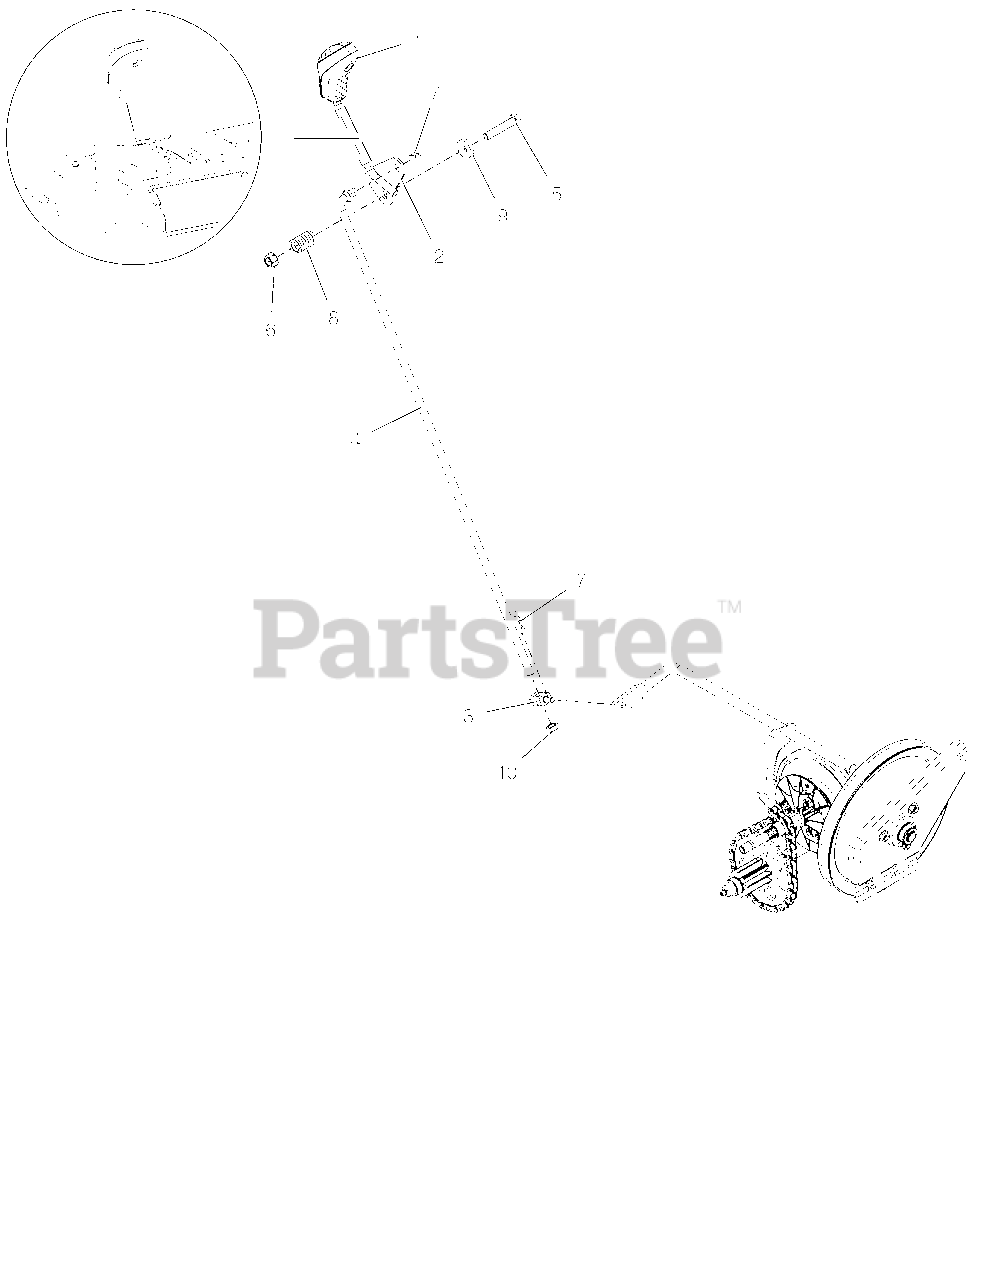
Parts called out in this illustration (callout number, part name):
1	KNOB, CONTROL, DASH
2	WELDMENT,LG DASH SPEED CONTROL
3	PIVOT,SHIFT ROD .375-16(TRUNN)
4	ROD, SHIFT-PRO
5	@BLT-HEX .38-16X2.00 GR5 YWZC
6	@NUT-LK-TOP-FLG .38-16 YWZC
7	PIN-HAIR INT .08X.18X1.18 YWZC
8	SG-COMP .125X.781X1.250
9	WSHR-FL-STL .406X1.00X.188 YWZ
10	NUT-HEX-JAM .375-16 YWZC
